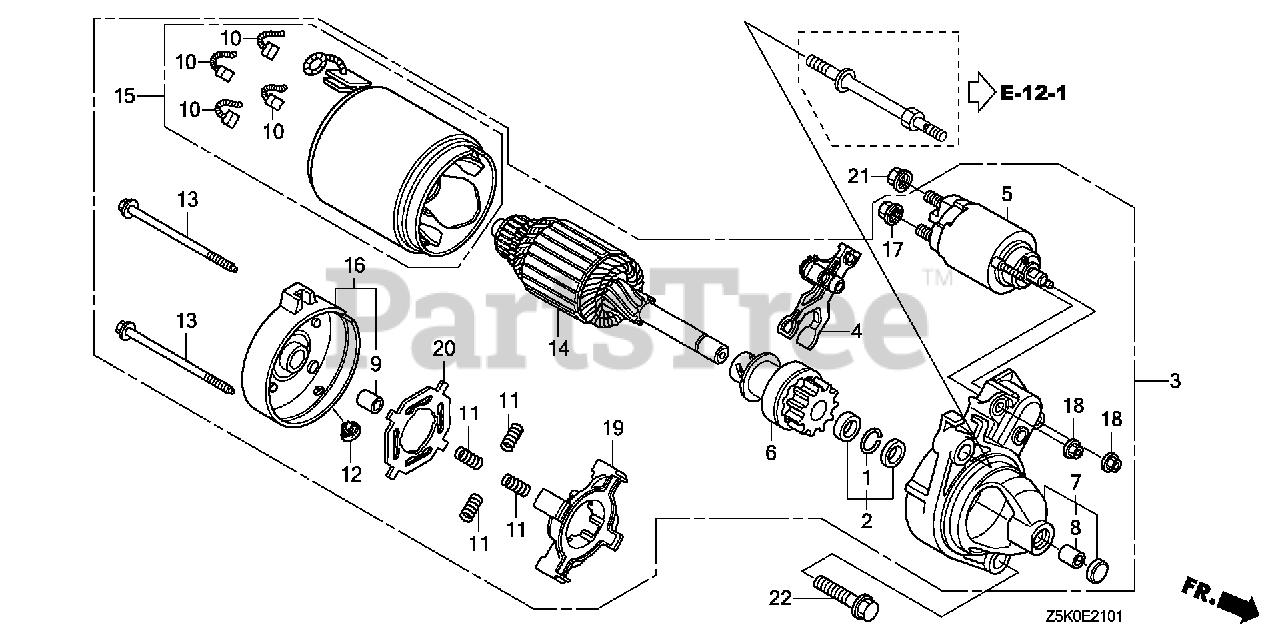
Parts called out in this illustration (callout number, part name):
1	RING, SNAP (DENSO)
2	COLLAR SET, CLUTCH STOP
3	STARTER MOTOR ASSY.
4	LEVER, PINION DRIVE
5	SWITCH ASSY., MAGNET
6	CLUTCH, OVERRUNNING
7	HOUSING, DRIVE SIDE
9	BEARING B
10	BRUSH
11	SPRING, BRUSH
13	BOLT, THROUGH
16	FRAME, COMMUTATOR END
17	NUT, HEX. (8MM)
18	NUT, FLANGE (5MM)
19	HOLDER, BRUSH
20	INSULATOR, BRUSH HOLDER
21	NUT-WASHER (8MM)
22	BOLT, FLANGE (10X40)
